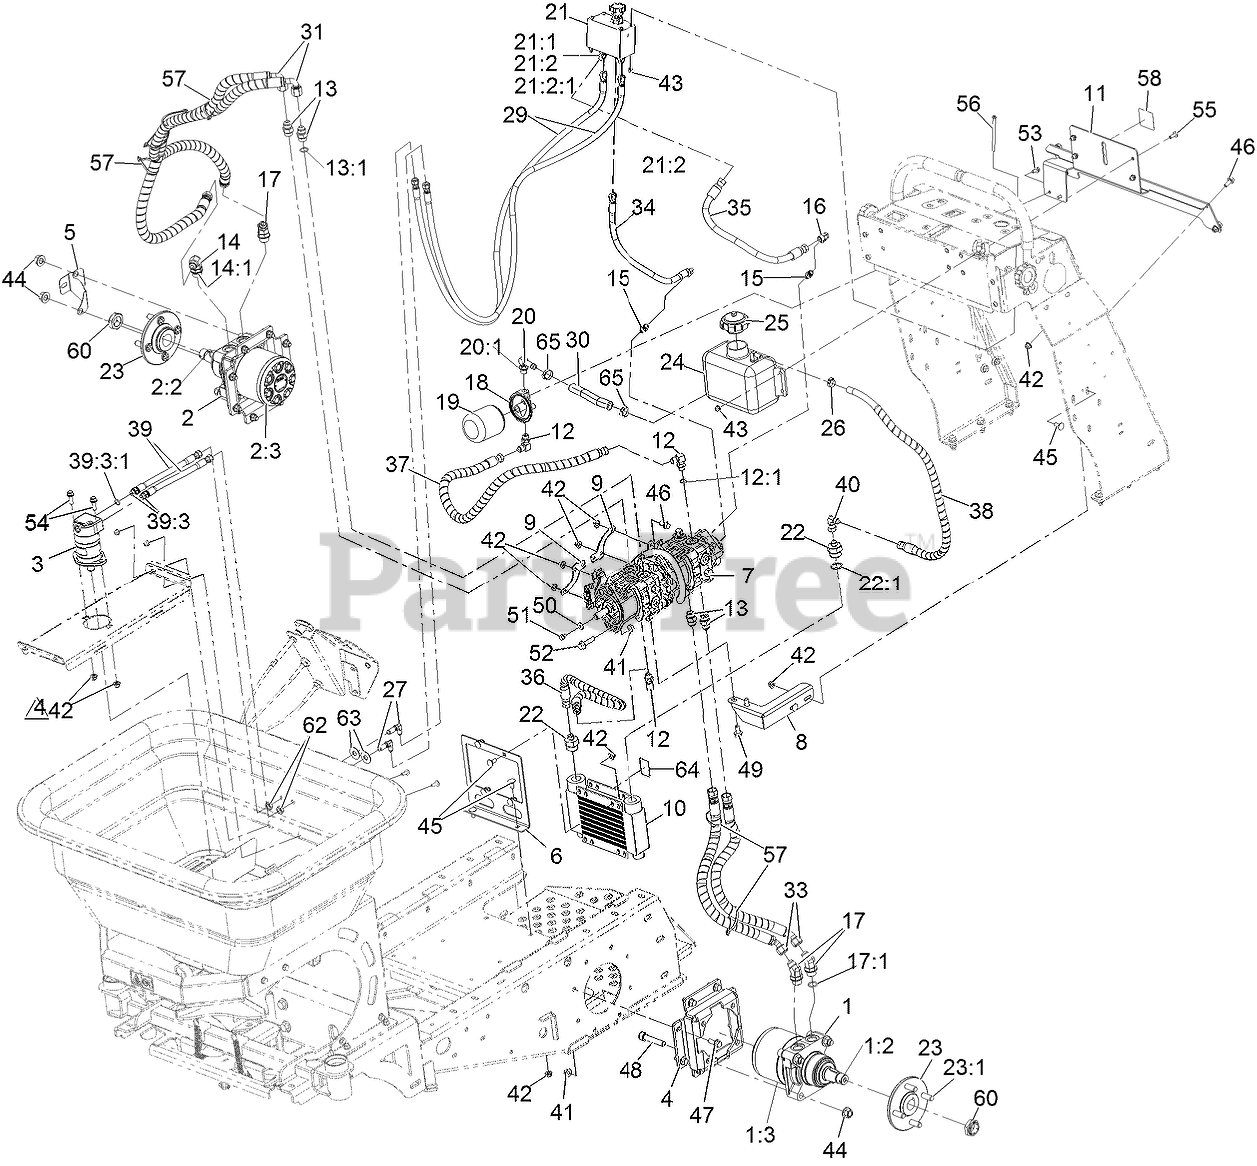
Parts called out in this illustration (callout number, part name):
1	MOTOR, LH WHEEL
1:2	KEY-WOODRUFF
1:3	SEAL KIT
2	MOTOR, RH WHEEL
2:2	KEY-WOODRUFF
2:3	SEAL KIT
3	MOTOR-HYDRAULIC, SPREADER
4	Mount-Motor, Wheel
5	BRACKET-HOPPER, SPEEDOMET
6	Mount-Cooler
7	PUMP-TANDEM
8	Bracket-Support, Hydro Pump
9	Extension, Hydro Pump
10	COOLER-OIL
11	Mount, Hydraulic Tank And Filter
12	FITTING-ELBOW, 90 DEG
12:1	O-RING
13	FITTING-STRAIGHT
13:1	O-RING
14	FITTING-90 DEG
14:1	O-RING
15	FITTING-STRAIGHT
16	FITTING-90 SWIVEL
17	FITTING-ELBOW, 45 DEG
17:1	O-RING
18	HEAD-FILTER
19	FILTER-25 MICRON, BI-DIRECTIONAL
20	FITTING-ELBOW, 90
20:1	O-RING
21	Manifold-Flow Control, Hopper
21:2	FITTING-ELBOW, 45 DEG
21:2:1	O-RING
22	ADAPTER-STRAIGHT
22:1	O-RING
23	HUB-WHEEL
23:1	STUD-1/2-20 X 1.55
24	TANK-HYDRAULIC, PLASTIC
25	Cap-Vented
26	CLAMP-OETIKER, 167
27	FITTING-ELBOW, 90
29	Hose ASM, HYD HP
30	HOSE-HYDRAULIC
31	HOSE ASM-HYD HP
33	HOSE ASM-HYD HP
34	Hose ASM-HYD HP
35	Hose ASM, HYD LP
36	Hose ASM, HYD LP
37	Hose ASM, HYD LP
38	Hose ASM, HYD LP
39	Hose ASM-HYD HP
39:3	Fitting-Straight, Rigid
39:3:1	O-RING
40	ELBOW-SWIVEL, 90 DEG
41	Nut-Hex Flange
42	Nut-Hex Flange
43	Nut-Hex Flange
44	Nut-Lock 1/2-13
45	SCREW-CARR
46	SCREW-HHF
47	SCREW-HHF
48	Screw-HSH
49	SCREW-HHF
51	SCREW-HHF
52	SCREW-HHF
53	SCREW-HHF
54	SCREW-HHF
55	Screw-Hsbhf
56	Screw-HSBH
57	TIE-CABLE
58	DECAL-OIL
60	LOCKNUT
62	Nut-Jam
63	Washer-SS, 1.25 OD, .503 ID
64	DECAL-WARNING
65	CLAMP-OETIKER, 167
